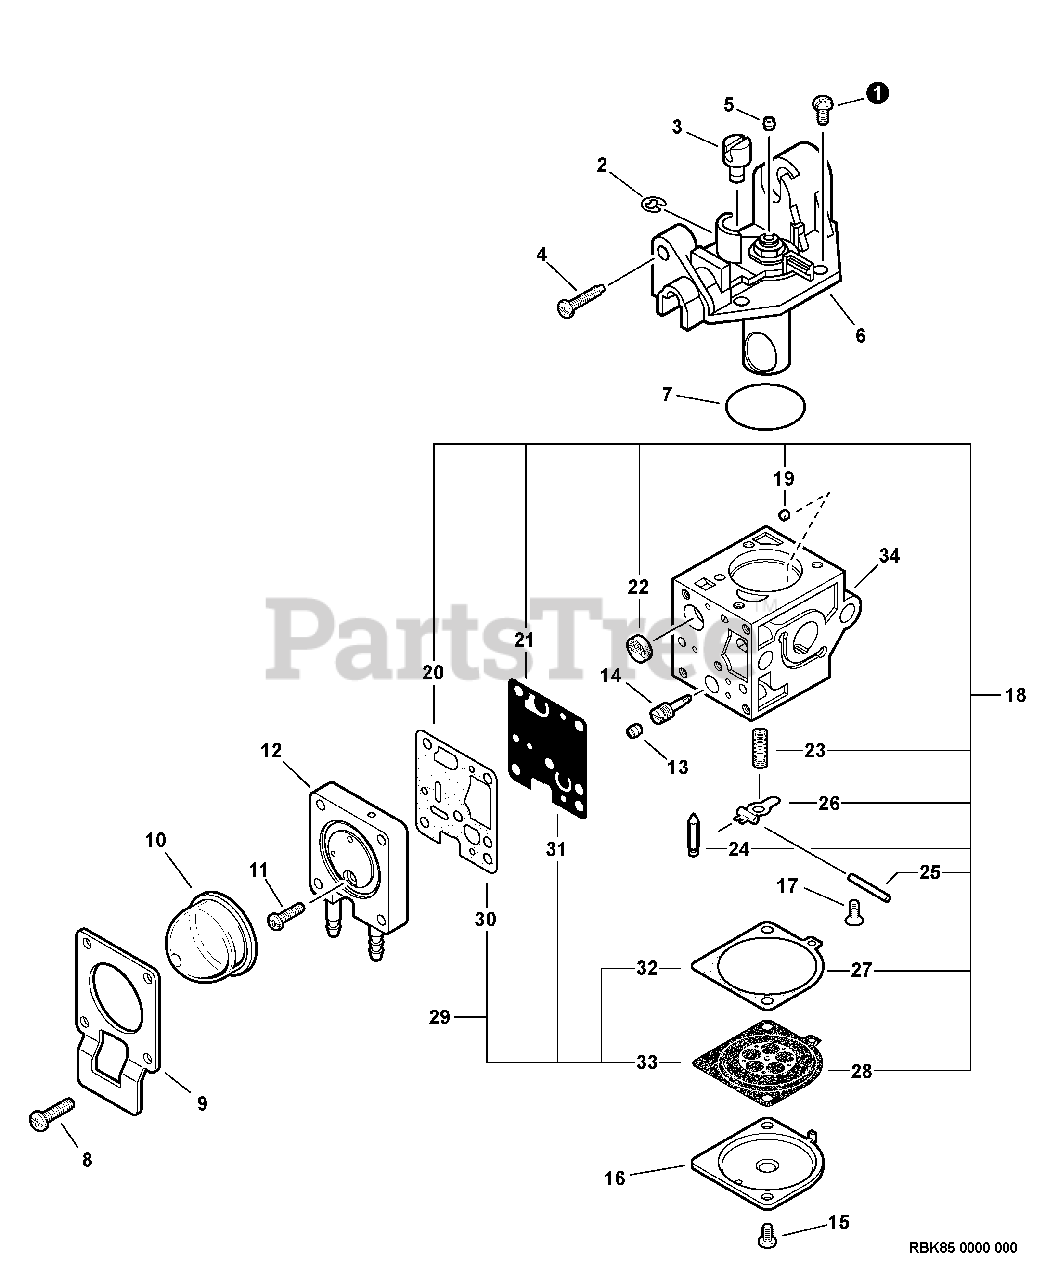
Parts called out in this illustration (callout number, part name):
2	RING, RETAINING
4	SCREW, IDLE ADJUST
6	ROTOR COVER ASSY
8	SCREW, RETAINER
9	RETAINER, PURGE BULB
10	BULB, PURGE
11	SCREW, PURGE BASE
12	BASE, PURGE
14	NEEDLE - HIGH SPEED
16	COVER, METERING
17	SCREW, METERING LEVER PIN
18	REPAIR KIT
19	GUIDE, ROLLER
20	GASKET, PUMP
21	DIAPHRAGM, PUMP
22	STRAINER
23	SPRING, METERING LEVER
24	VALVE, INLET NEEDLE
25	PIN, METERING LEVER
26	LEVER, METERING
27	GASKET, DIAPHRAGM
28	DIAPHRAGM, METERING
29	DIAPHRAGM/GASKET KIT
30	GASKET, PUMP
31	DIAPHRAGM, PUMP
32	GASKET, DIAPHRAGM
33	DIAPHRAGM, METERING
34	BODY, CARBURETOR
